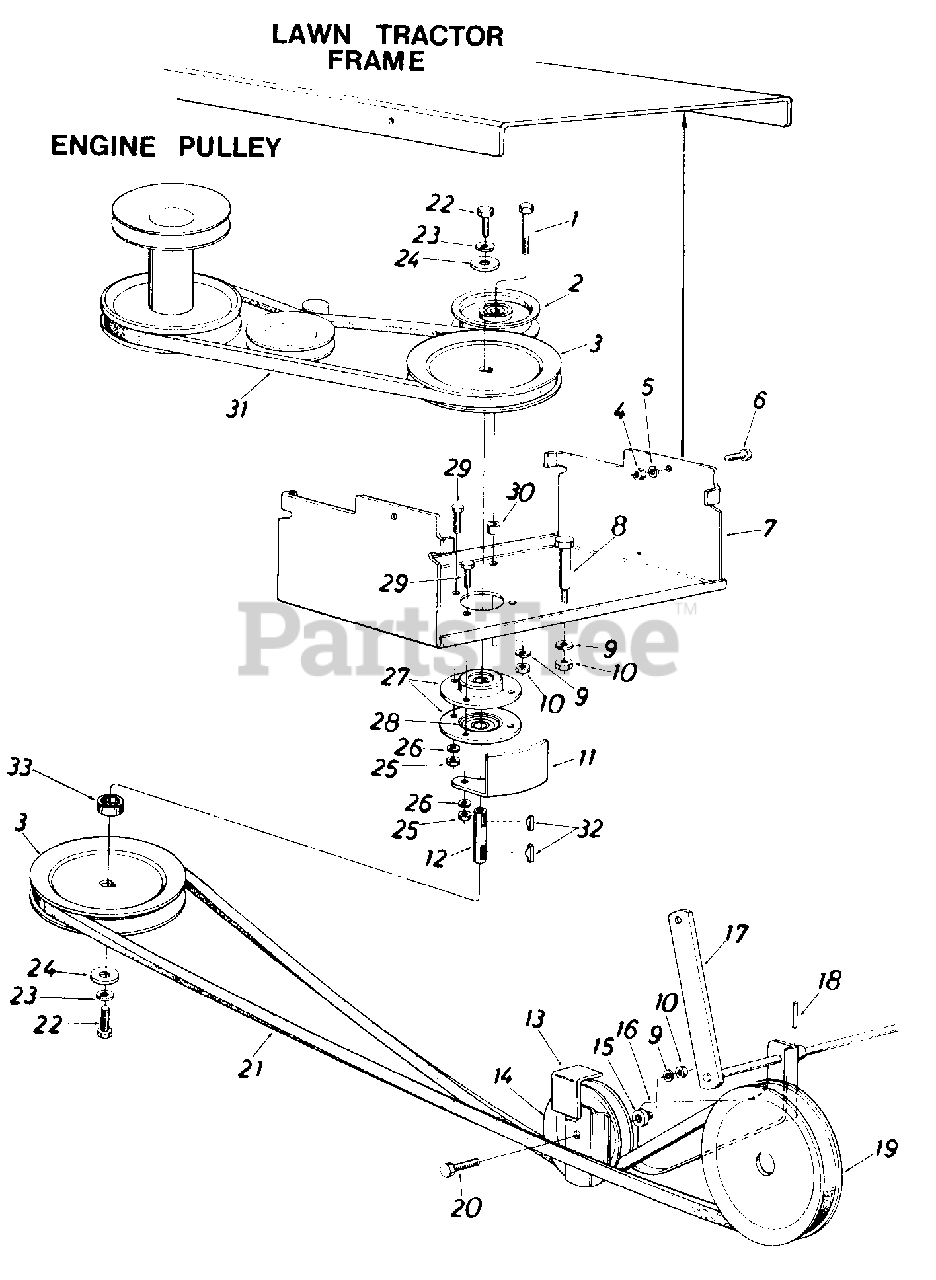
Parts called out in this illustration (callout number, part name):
1	Hex Bolt 3/8-16x 2.00" Lg.*
2	Fl.-Idler w/Flanges 3-3/4" O.D.
3	5/8" "V"-Pulley.790" I.D. x .650" O.D.
4	Hex Nut 3/8-24 Thd.*
5	L.-Wash. 3/8" I.D. Heavy Duty
6	Hex Bolt 3/8-24x.88" Lg.*
7	Carriage Bracket
8	Shoulder Bolt .498" Dia. x 1 .64
9	L.-Wash. 3/8" I.D.*
10	Hex Nut 3/8-16 Thd.*
13	Belt Separator Plate
14	Fl.-Idler w/Flanges 3.25"O.D.
15	Fl.-Wash. .406" I.D. x 1.25" O.D. x .164
18	Spring Pin Roll 3/16" Dia. x 1 50" Lg.
19	5/8" V-Pulley 1.50" I.D. x 6.50" O.D.
20	Hex Bolt 3/8-16 x 1.75" Lg.*.
21	"V"-Belt 1/2" x 95.0" Lg.
22	Hex Bolt 5/16-18 x .88" Lg. Spec.
23	L.-Wash. 5/16" 1.D.*
24	Fl.-Wash. .344" I.D. x 1.125" O.D. x .125
25	Hex Nut 5/16-18 Thd.*
26	L.-Wash. 5/16" I.D.*
27	Bearing Housing 1.85" I.D.
28	Ball Bearing .787" I.D. x 1.85" O.D.
29	Hex Sems Bolt 5/16-18 x .75"
30	Spacer
31	Belt 1/2" Wide x 52" Long
32	Hi-Pro Key 3/16" x 5/8"
33	Spacer-.80" I.D. x 1.0" O.D.
